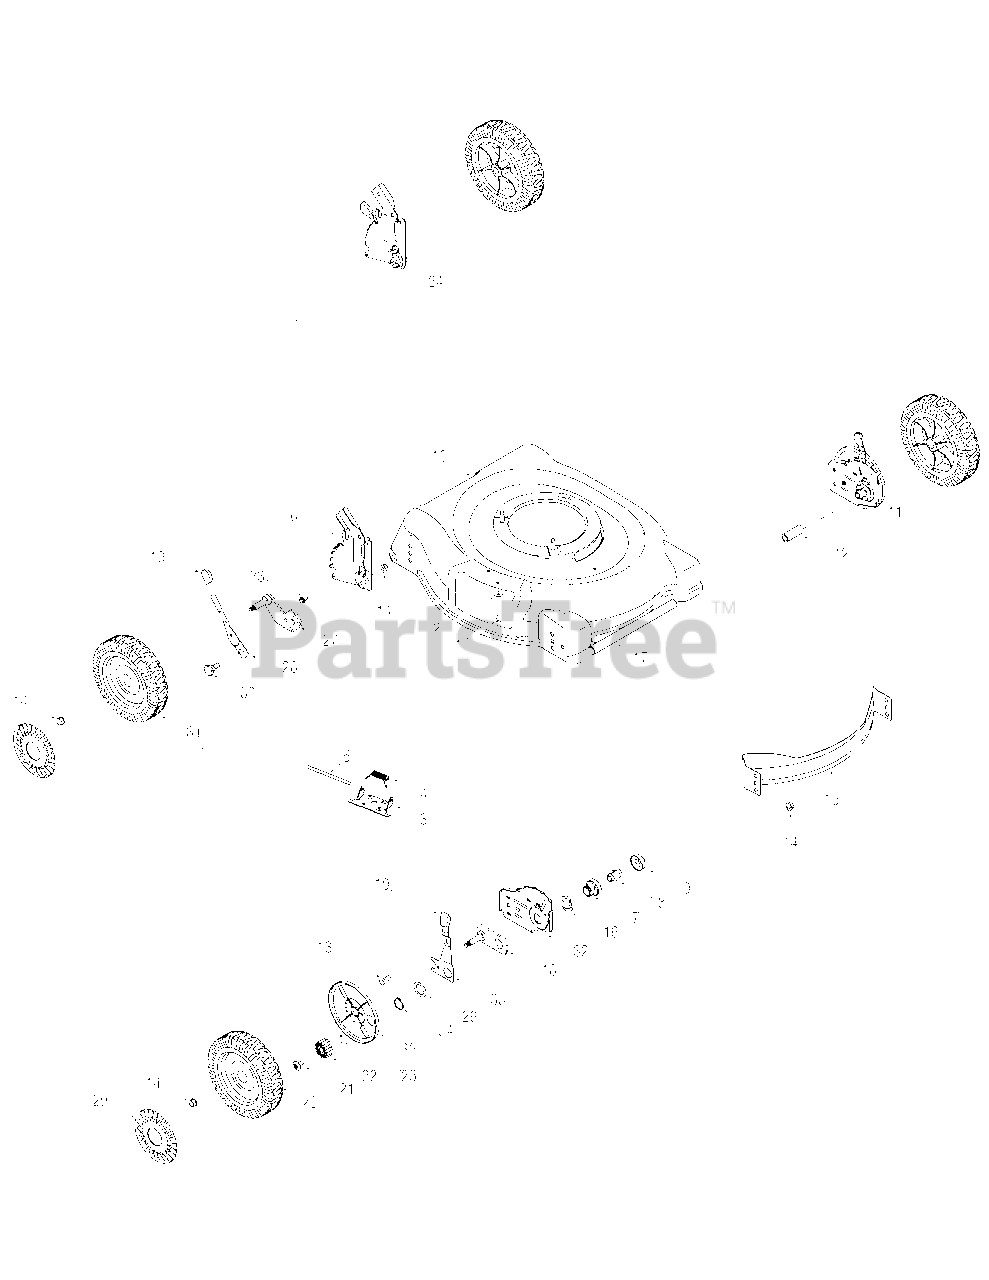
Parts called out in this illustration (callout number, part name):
1	TT Screw 1/4-20 x 0.5
2	Bell Washer.265 x 0.75
3	Deflector Chute Adapter
4	Torsion Spring
5	Hinge Pin
6	Handle Bracket - RH
7	Bearing Support
8	Bearing Sleeve
9	Bearing Retainer
11	Height Adjustment Assembly
12	Slev. Spacer 1.8" Lg.
13	Hex Screw, 3/8-16 x.75
14	Flange Lock Nut, 3/8-16
15	Front Baffle
16	Wave Washer
17	Sleeve Spacer 9.10" Lg.
18	Pivot Plate Assembly
19	Adjustment Knob
20	Front Wheel w/ Fitting, 8 x 2.125
21	Screw, 1/4-20 x .390
22	Gear 14T RH FWD
23	TT Scr. w/Washer 1/4-20 x. .625
24	Handle Bracket Assembly - LH
25	Dowel Pin
27	Pivot Arm Assembly - RH
28	Rear Spring Lever
29	Hub Cap
30	Shoulder Scr.500 Dia. x.434
31	Rear Wheel, 8 x 2.125
32	Height Adjuster Plate - RH
33	Front Lever - RH
34	Snap Ring
35	Wheel Dust Cap
